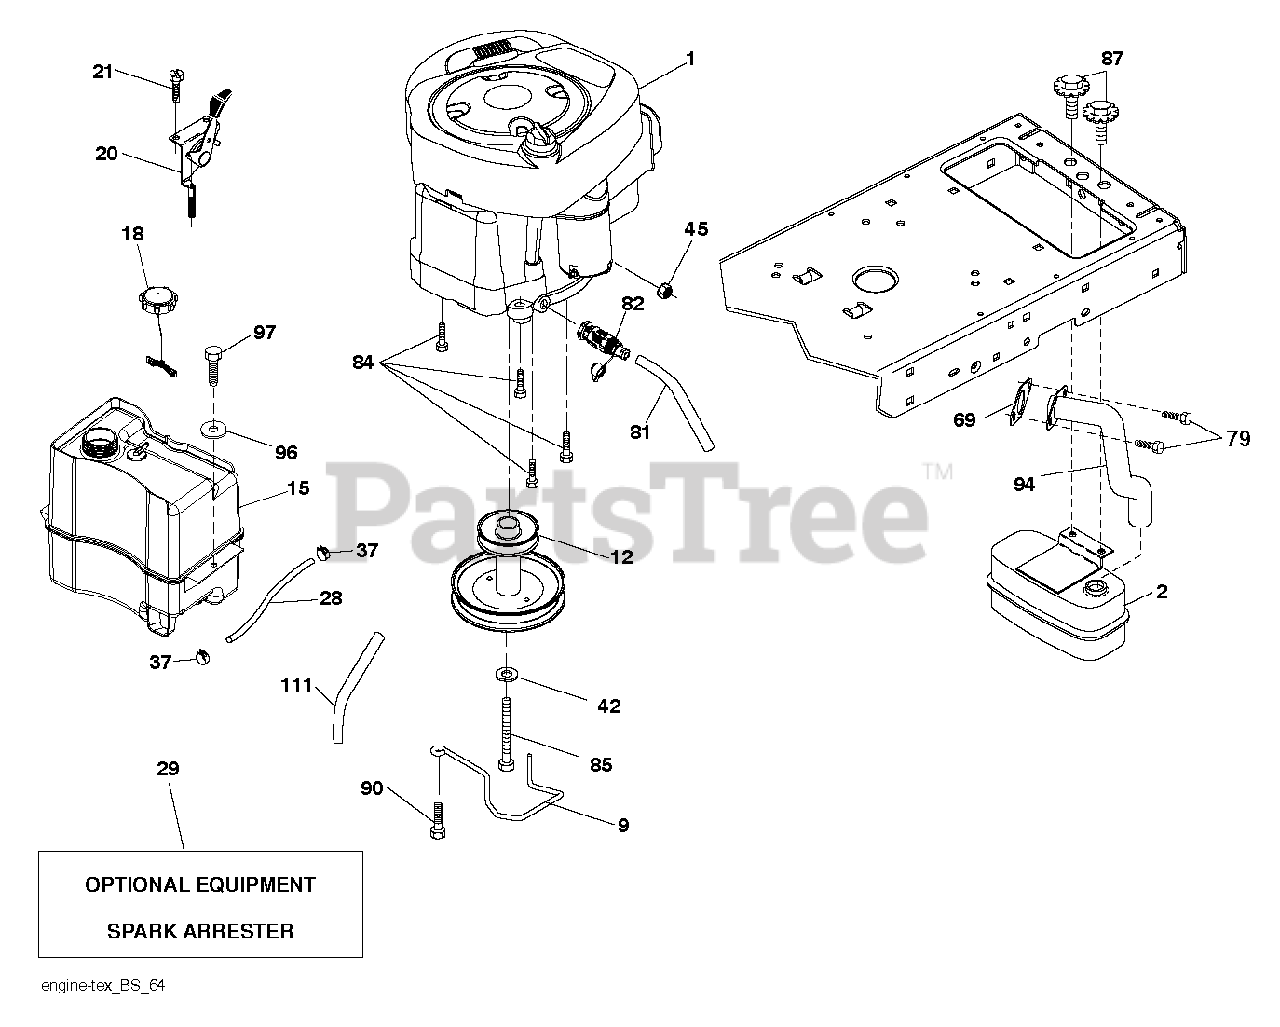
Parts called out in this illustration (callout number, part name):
2	MUFFLER.SINGLE.CYL.KOHL/B&S
9	KEEPER.BELT.ENGINE.3.25
12	PULLEY ENGINE
15	TANK.ASM.1.5GAL.FRT.W/CAP.EPA
18	CAP.FUEL.2 WAY VENT
21	SCREW.#10 X 0.750.BOS (2 2)
28	LINE.FUEL.20"FRONT.EMI
29	SPARK ARRESTOR KIT
37	HOSE CLAMP
42	LOCKWASHER
45	NUT
79	SCREW.SOCKET HD.5/16-1
81	TUBE, DRAIN OIL ASM.
82	VALUE.OIL.DRAIN
84	SCREW.3/8-16
85	BOLT HEX 7/16-20X4-1/4"
87	BOLT, 5/16-18 X 1 3/4
90	SCREW 3/8-16X1
94	RP.EXHAUST.TUBE.B&S.28/31
97	SCREW HEXWSHR 1/4-20X3/4
111	RP PURGE LINE
